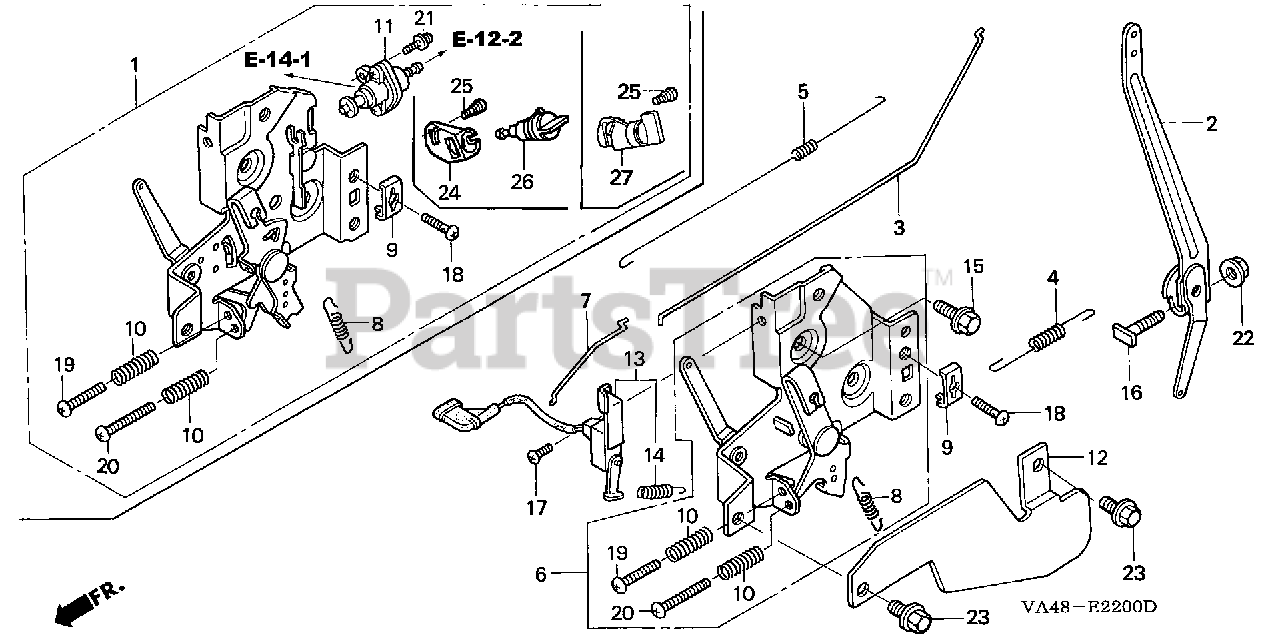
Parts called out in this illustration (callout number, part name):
2	ARM, GOVERNOR
3	ROD, GOVERNOR
4	SPRING, GOVERNOR
5	SPRING, THROTTLE RETURN
6	CONTROL
7	ROD, CHOKE
8	SPRING, LEVER
9	HOLDER, CABLE
10	SPRING, CONTROL ADJUSTING Use from Engine SN 2327377.
12	PROTECTOR, CONTROL
13	SWITCH ASSY., ENGINE STOP
14	SPRING, SWITCH CONTROL
15	BOLT, FLANGE (6X14)
16	BOLT, GOVERNOR ARM
17	SCREW, PAN (4X8)
18	SCREW, PAN (5X16)
19	SCREW, PAN (5X20)
20	SCREW, PAN (5X25)
22	NUT, FLANGE (6MM)
23	BOLT, FLANGE (6X10)
